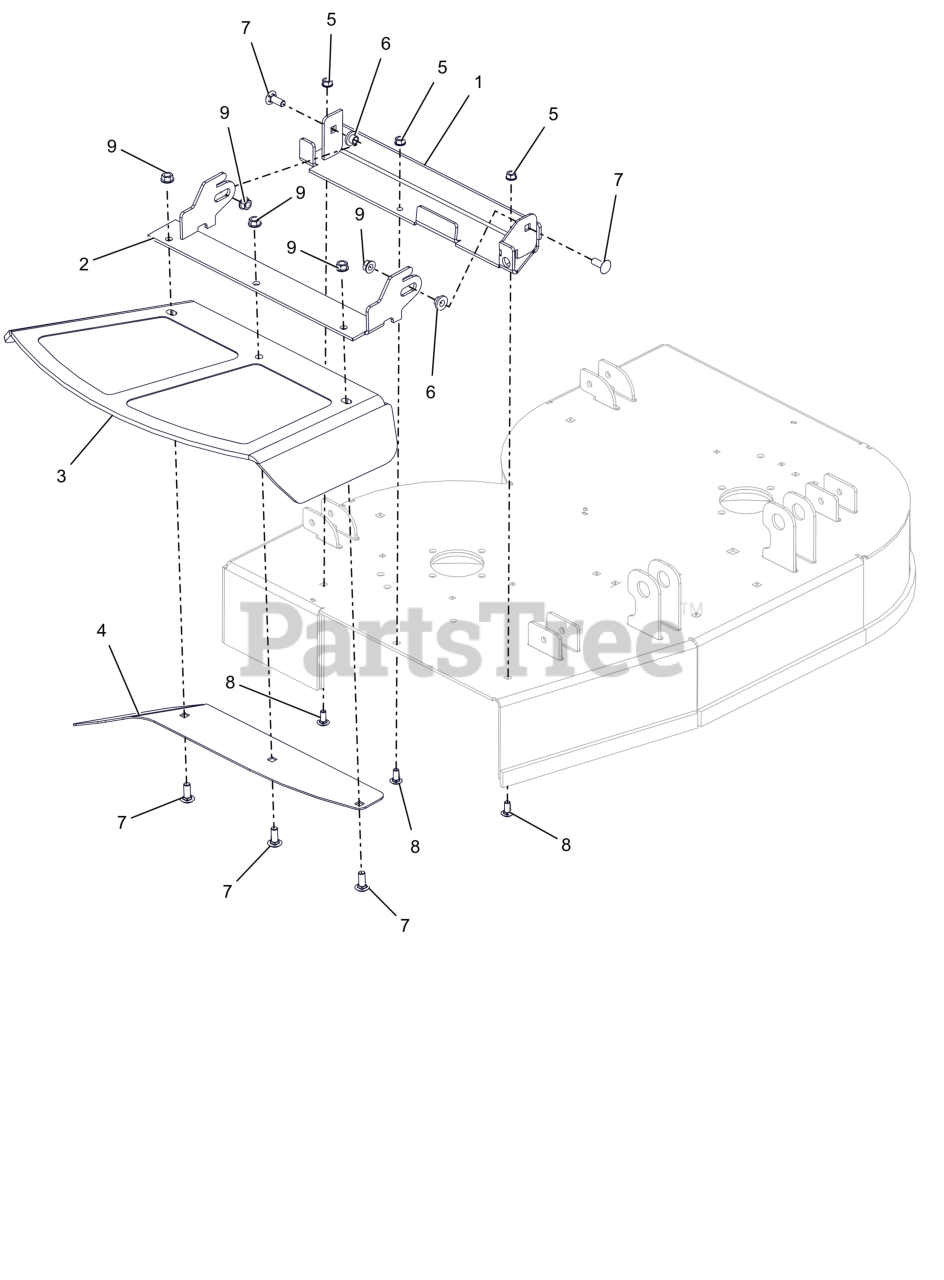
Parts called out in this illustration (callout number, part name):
1	WLDMT, DISCHARGE CHUTE (RED)
2	WLDMT, 36" CHUTE MTG BRKT (RED)
3	CHUTE,48-60" FRMD RUBBER DISCH
4	PLATE, 32-36" DISCH CHUTE CLAMP (BLACK)
5	NUT,LK-CTR-FLG .31-18 GF ZCC
6	BSHG-FLG .385X.500X.875X.406
7	BLT,RHSSN .38-16X1.00 G5 ZCC
8	BLT, RHSSN.31-18X.750 G5 ZCC
9	NUT-LK-CTR-FLG .375-16 GF ZCC
